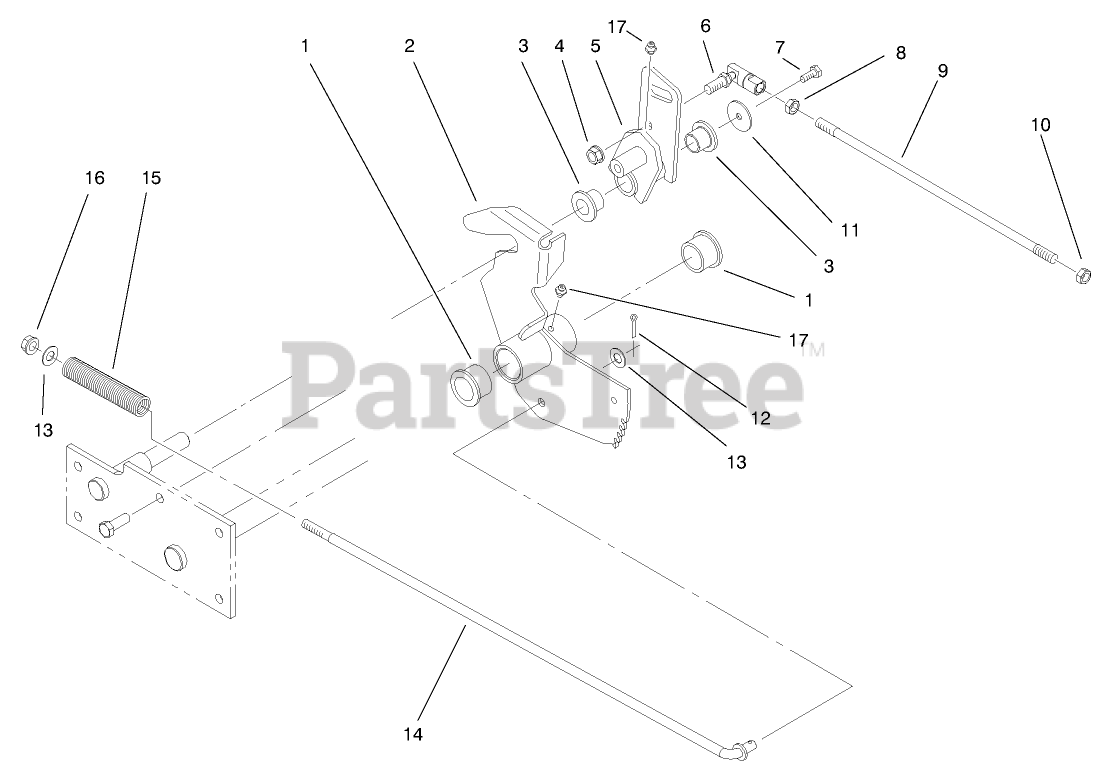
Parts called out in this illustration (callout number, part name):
1	BUSHING-FLANGED
2	PLATE-PIVOT, BRAKE
3	BUSHING
4	NUT-LOCK
5	PIVOT-HYDRO
6	END-TIE ROD, LH
7	SCREW-HH
8	NUT-HEX JAM, LH
9	ROD-PIVOT TO PEDAL
10	NUT-HJ
11	WASHER-FLAT
12	PIN-COTTER
13	WASHER-FLAT
14	ROD-BRAKE
15	SPRING-COMPRESSION
16	NUT-LOCK, NI
17	FITTING-GREASE
